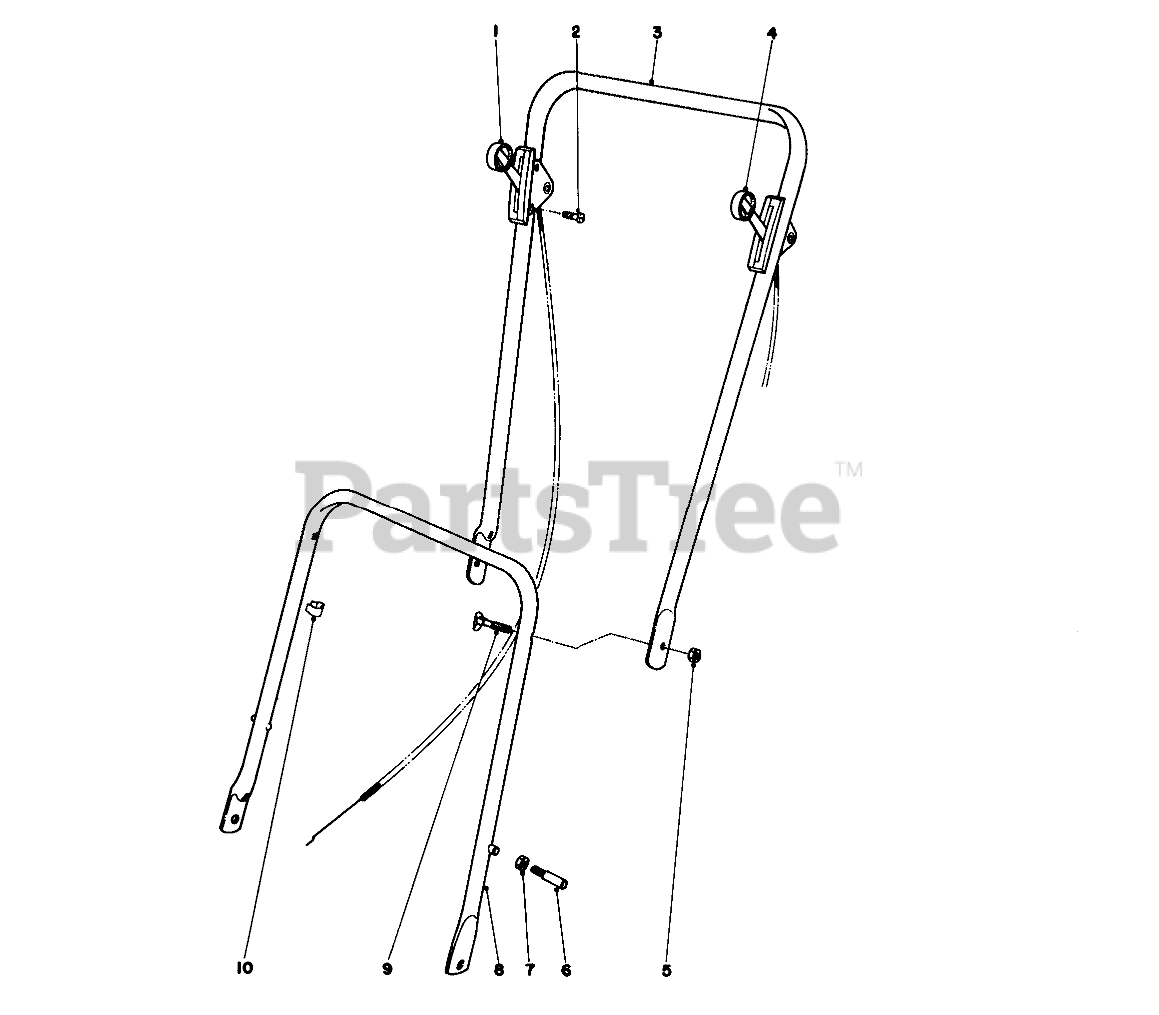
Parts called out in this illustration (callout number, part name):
1	SERVICE THROTTLE CONTRO
2	10-24 X 1 PAN HD SCR
3	Handle-Upper
4	Traction Control
5	Nut
6	HANDLE PIN
7	Nut
8	LWR HANDLE STAKED ASM
9	1-1/4 LG HANDLE SCREW
10	CONTROL WIRE CLIP
